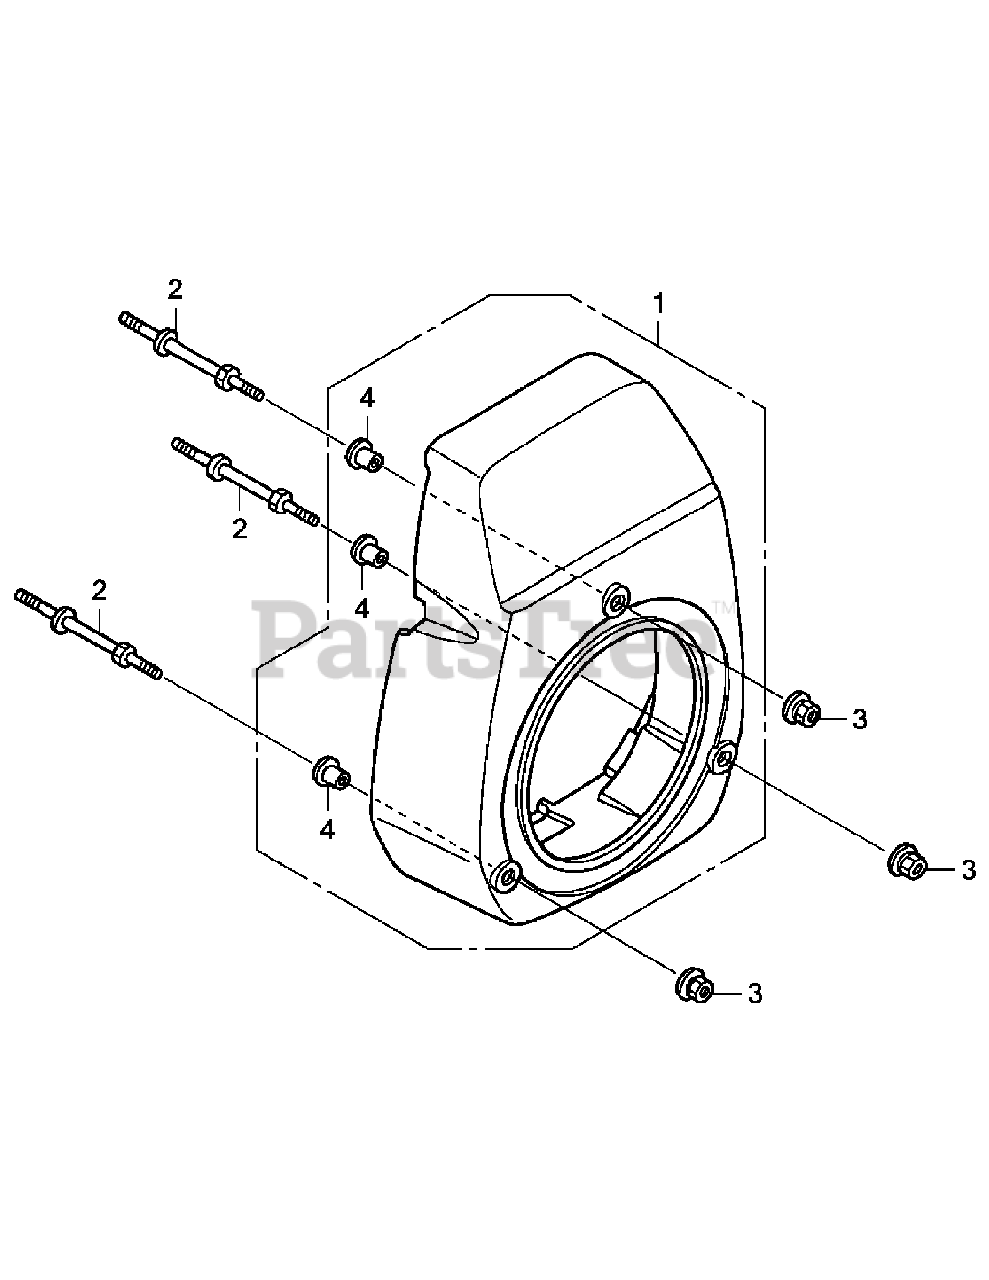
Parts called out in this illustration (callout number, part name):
1	COVER, FAN *NH1* (BLACK)
2	BOLT, STUD
3	NUT, FLANGE (6MM)
4	COLLAR, FAN COVER
